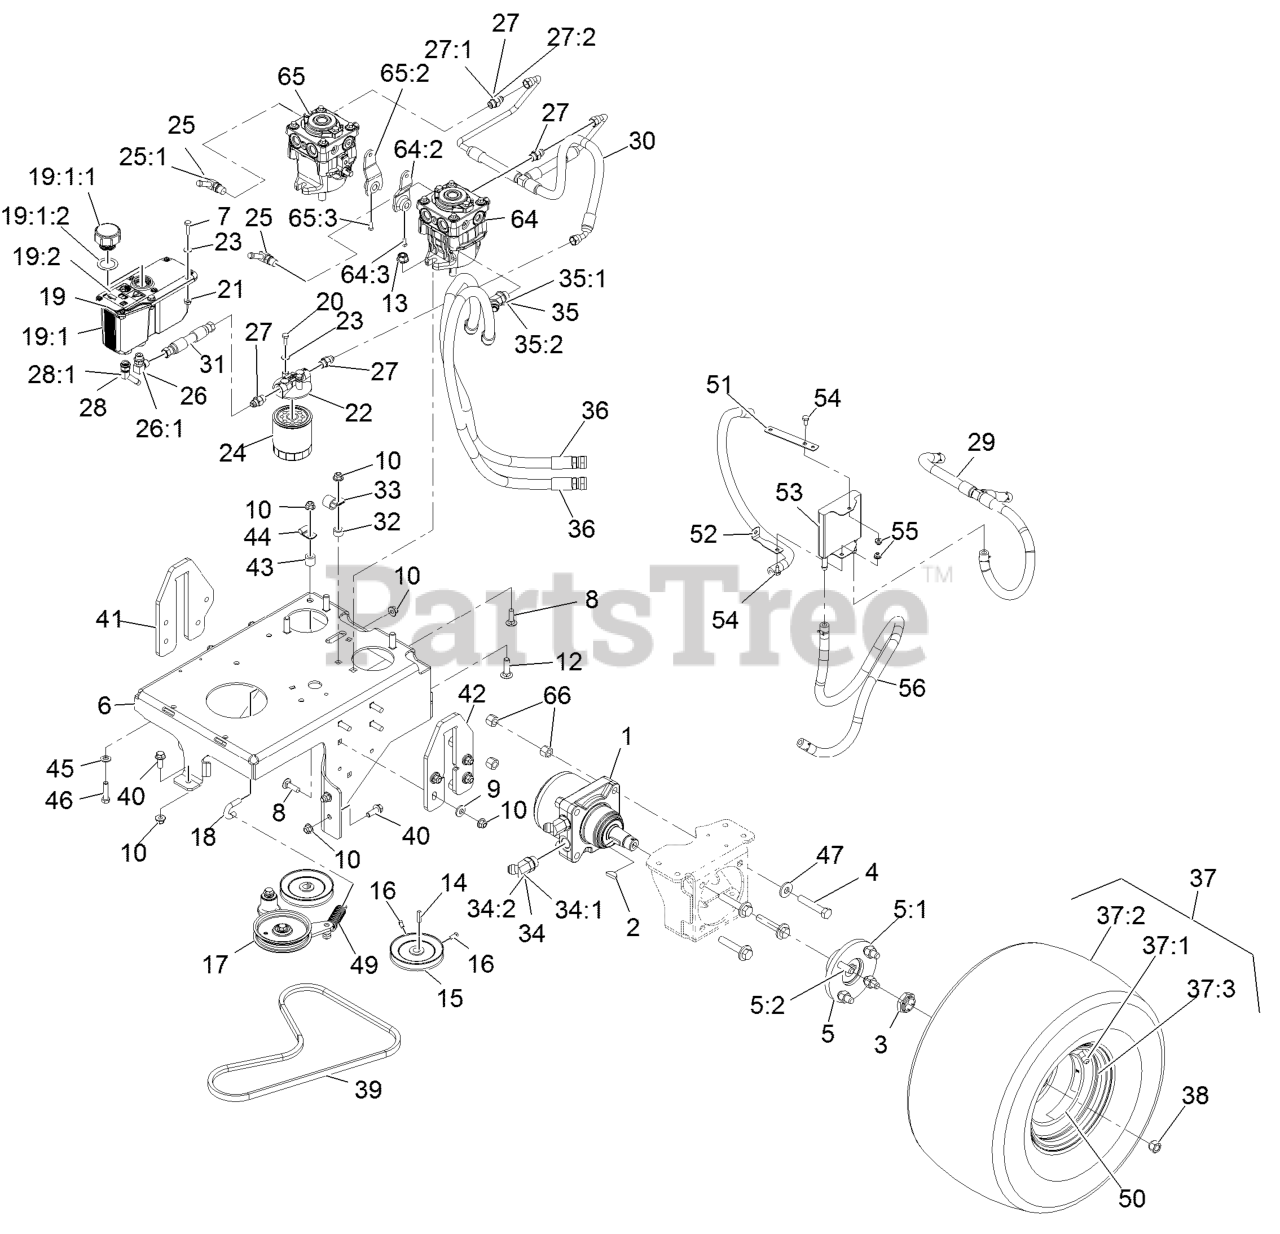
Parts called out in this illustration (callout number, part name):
1	MOTOR-WHEEL
2	KEY-WOODRUFF
3	LOCKNUT
4	SCREW-HH
5	WHEEL HUB / STUD ASM
5:1	HUB-WHEEL
5:2	STUD-TYPE, DRIVE
6	WELDMENT, FRAME
7	SCREW-HH
8	BOLT-CARR
9	WASHER-BELLEVILLE
10	NUT-HF, NI
12	SCREW-HH
13	NUT-HF, NI
15	PULLEY-PUMP
16	SCREW-SET
17	PUMP IDLER ASM
18	ANCHOR, SPRING
19	RESERVOIR ASM
19:1	Reservoir-Hyd
19:1:1	Cap-Reservoir, HYD
19:1:2	GASKET-CAP
19:2	DECAL-WARNING
20	SCREW-HH
21	NUT-HHF
22	HEAD-FILTER
23	WASHER-FLAT
24	FILTER-25 MICRON, BI-DIRE
25	FITTING-ELBOW, 90
25:1	O-RING
26	FITTING-ELBOW, 90 DEG
27	FITTING-STRAIGHT
28	FITTING-BARBED, 45 DEG
28:1	O-RING
29	HOSE ASM-CASE DRAIN
30	HOSE ASSEMBLY - CHARGE
31	HYD HOSE ASM
32	SPACER-WHEEL
33	CLIP-LOOM
34	FITTING-HYD, 45 DEG
35	FITTING-HYD, 45 DEG
36	HYD HOSE ASM
37	WHEEL/TIRE ASM
37:1	RIM-8 INCH
37:3	Stem-Valve
38	NUT-LUG
39	BELT-V, LOWER PTO
40	SCREW-HHF 3/8-16 X 1
41	PLATE-LIFT, RH
42	PLATE, LIFT LH
44	CLIP-TUBE
45	WASHER-FLAT
46	SCREW-HH
47	WASHER-SPRING
49	SPRING-EXTENSION
50	DECAL-TORQUE, WHEEL HUB LUG
51	BRKT-COOLER MOUNT, TOP
52	BRKT-COOLER MOUNT, BOTTOM
53	COOLER-OIL
54	SCREW-HH
56	HOSE ASM
64	PUMP W/ARM - LEFT
64:2	ARM-HYDRO
64:3	SCREW-SET
65	PUMP W/ARM -RIGHT
65:2	ARM-HYDRO
65:3	SCREW-SET
66	NUT-LOCK, NI
